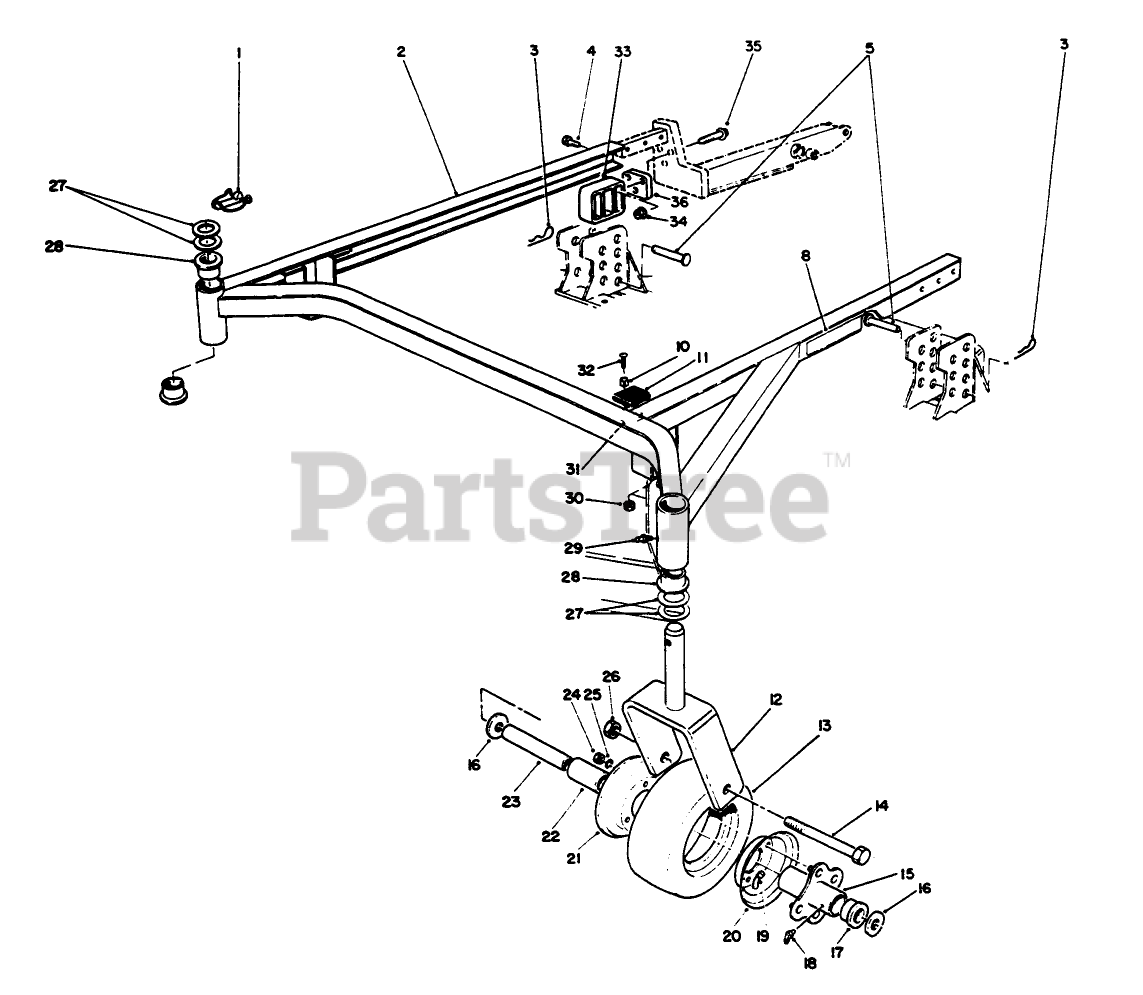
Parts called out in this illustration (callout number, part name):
1	PIN-LYNCH
2	52-INCH CARRIER FRAME ASM
3	PIN-HAIR
4	SCREW-HH
5	PIN-CLEVIS
6	FITTING-GREASE, 90 DEG
8	DECAL-HOC, LH
10	SPACER
11	CUSHION-RUBBER
12	Castor Fork
14	SCREW-HH
15	HUB-CENTER
16	WASHER-FLAT
17	BEARING-OUTSIDE
18	FITTING-GREASE
19	TUBE-INNER (W/VALVE)
20	FEMALE WHEEL HALF
21	MALE WHEEL HALF
22	BEARING-ROLLER
23	SPANNER-TIRE
24	NUT-HEX
25	WASHER-LOCK
26	NUT-HEX
27	WASHER-THRUST
28	Bushing
29	FITTING-GREASE
30	NUT-LOCK, NI
31	SHIM-CUSHION
33	Cradle-Rear
34	NUT-FLANGE
35	SCREW-HHF, WHIZ
36	Spacer
